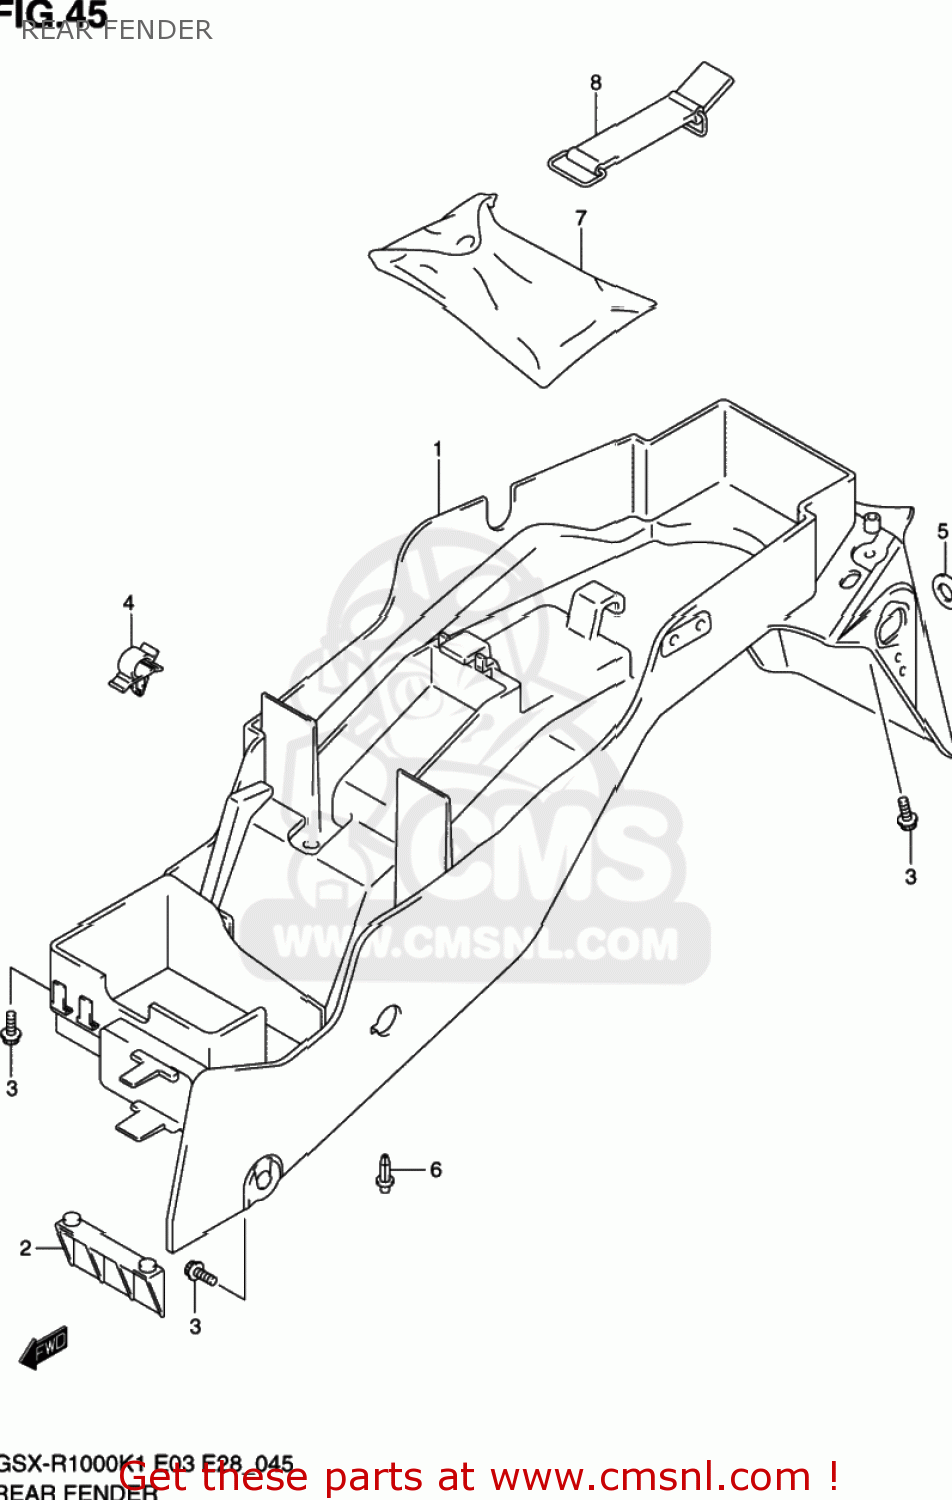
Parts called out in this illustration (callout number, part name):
1	FENDER,RR
2	MUD GUARD,REAR FENDER
3	BOLT(6X18)
4	CLAMP
5	WASHER(6.5X18X1)
6	CLIP(BLACK)
7	TOOL ASSY
8	BAND,TOOL
